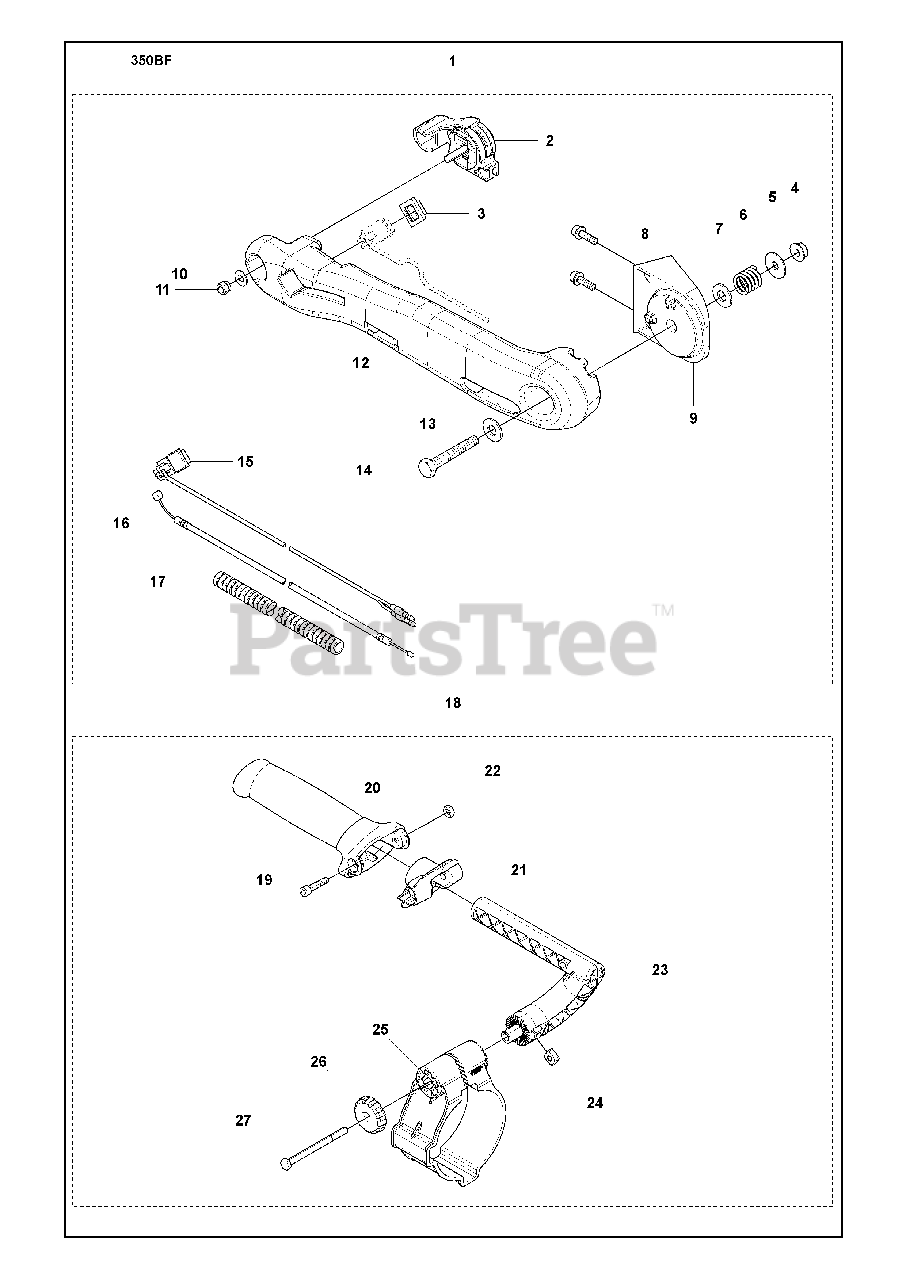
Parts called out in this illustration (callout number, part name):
1	HANDLE ASSY
2	LEVER
3	CAP
4	%NUT
5	WASHER
6	SPRING
7	WASHER
8	SCREW
9	RP_BRACKET
11	NUT
12	ARM
13	WASHER
14	BOLT
15	KILL SWITCH
16	CABLE COMP
19	SCREW
23	BRACKET
25	HOLDER TH
